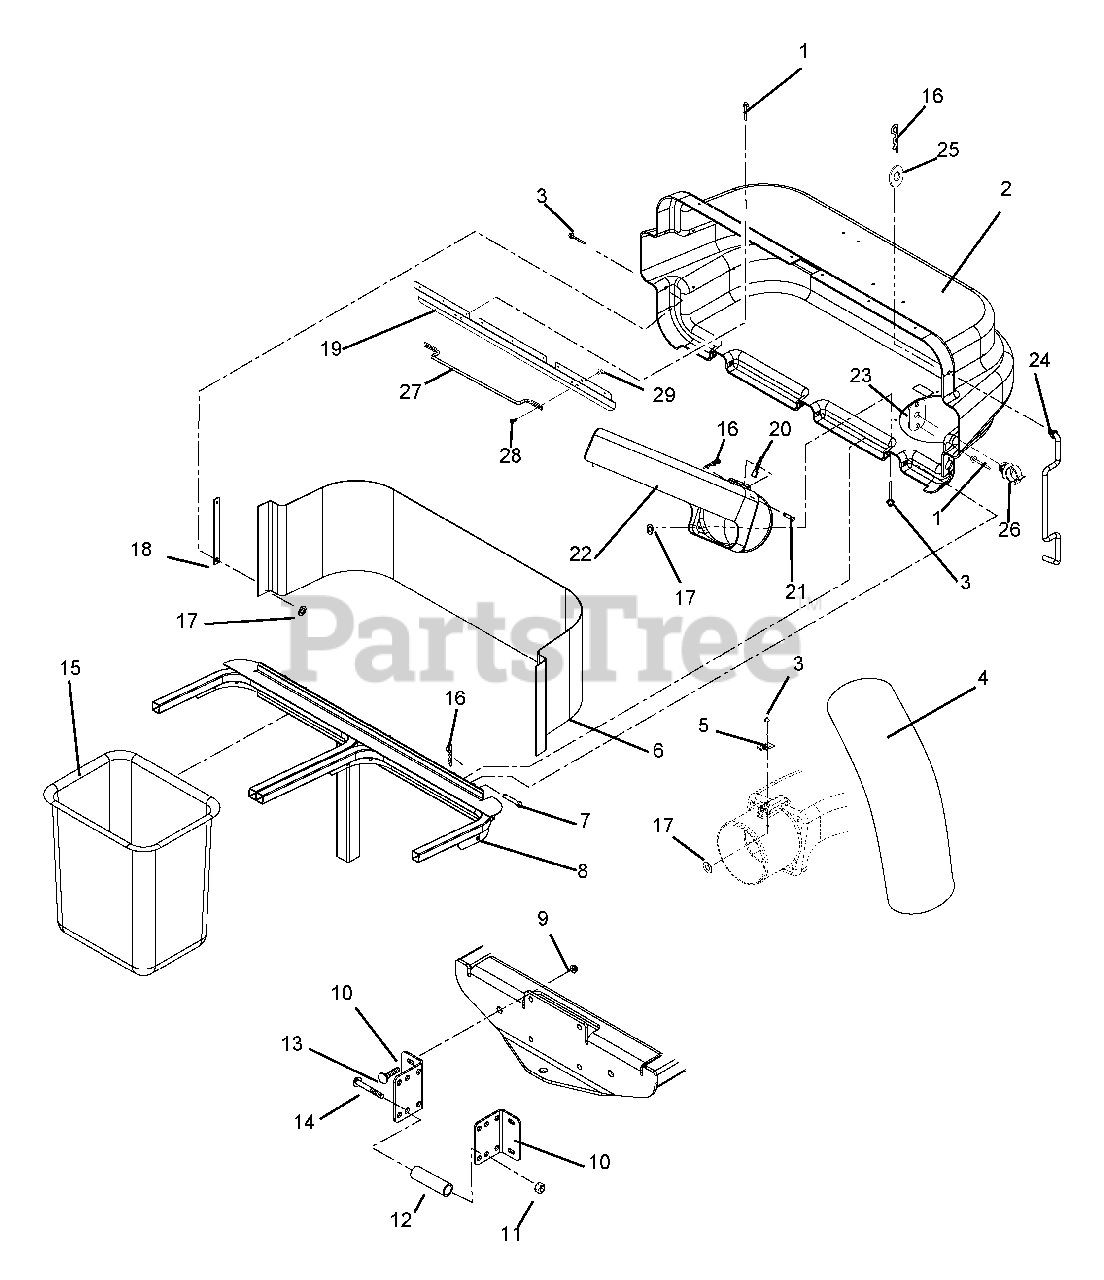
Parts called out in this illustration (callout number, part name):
1	Rivet-Pop .187 x .402
2	Cover, Bagger with Decal
3	Rivet-Pop .187 x .375
4	Hose 7 x 38
5	Thumb Latch
6	Screen, Bagger
7	Pin-Clevis .368/.373 x 3.25
8	Weldment, Bagger Frame
9	Nut-Locking-Top-Flange .38-16
10	Bracket, Bagger Mount
11	Nut-Locking-Top-Flange .50-13
12	Spacer, Pivot
13	Bolt-Round Head Square Neck .38-16 x 1.25 Grade 5
14	Bolt-Hex .50-13 x 3.00 Grade 5
15	Grass Bagger Basket
16	Pin-Hair
17	Washer-Flat-Steel .219 x .50 x .049
18	Strap, Cover
19	Latch, Cover
20	Indicator, Flow
21	Pin-Clevis .31 x 2.62 Grade 5
22	Boot, Upper
23	Plate, Rod Clip
24	Prop-Rod, Bagger
25	Washer-Flat-Steel .046 x .812 x .065
26	Clip .38
27	Bagger Handle
28	Bolt, Round Head Square Neck .25-20 x .75 Grade 5
29	Nut, Locking-Top-Flange .25-20
